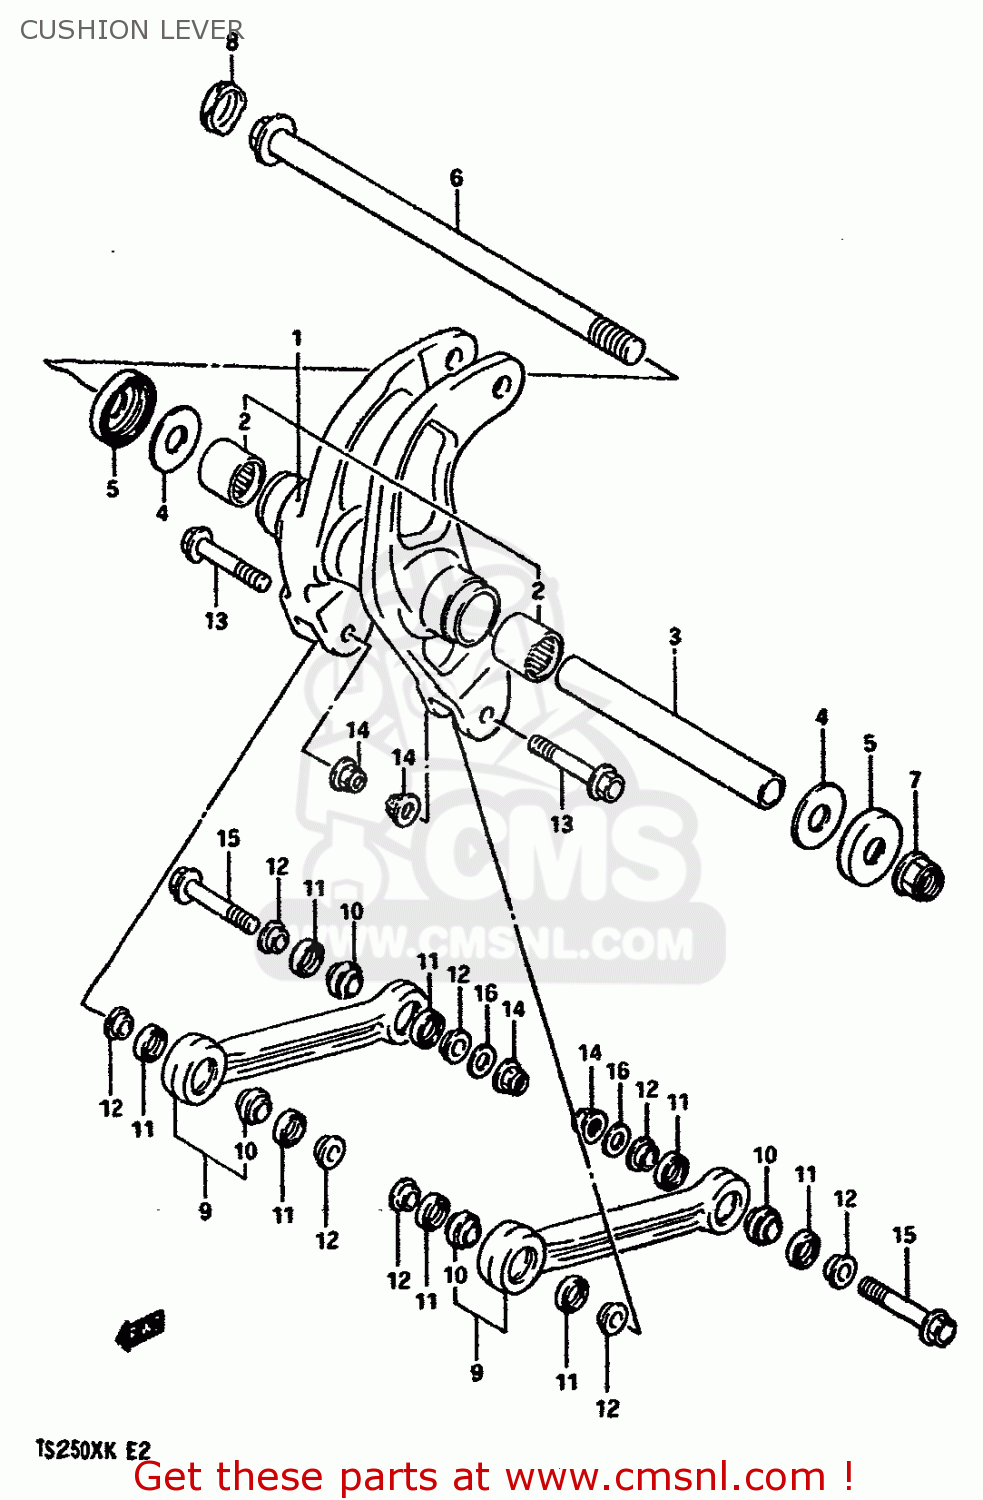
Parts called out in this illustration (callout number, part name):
1	LEVER SET,REAR CUSHION
2	BEARING(17X25X20)
3	SPACER
4	WASHER
5	DUST SEAL,REAR CUSHION,LEFT
6	SHAFT,REAR CUSHION LEVER
7	NUT 12MM
8	CAP,LEVER (BLUE)
9	ROD SET,CUSHION LEVER
10	BEARING(8X18X11)
11	DUST SEAL
12	SPACER
13	BOLT
14	NUT
15	BOLT 8X45
16	WASHER
